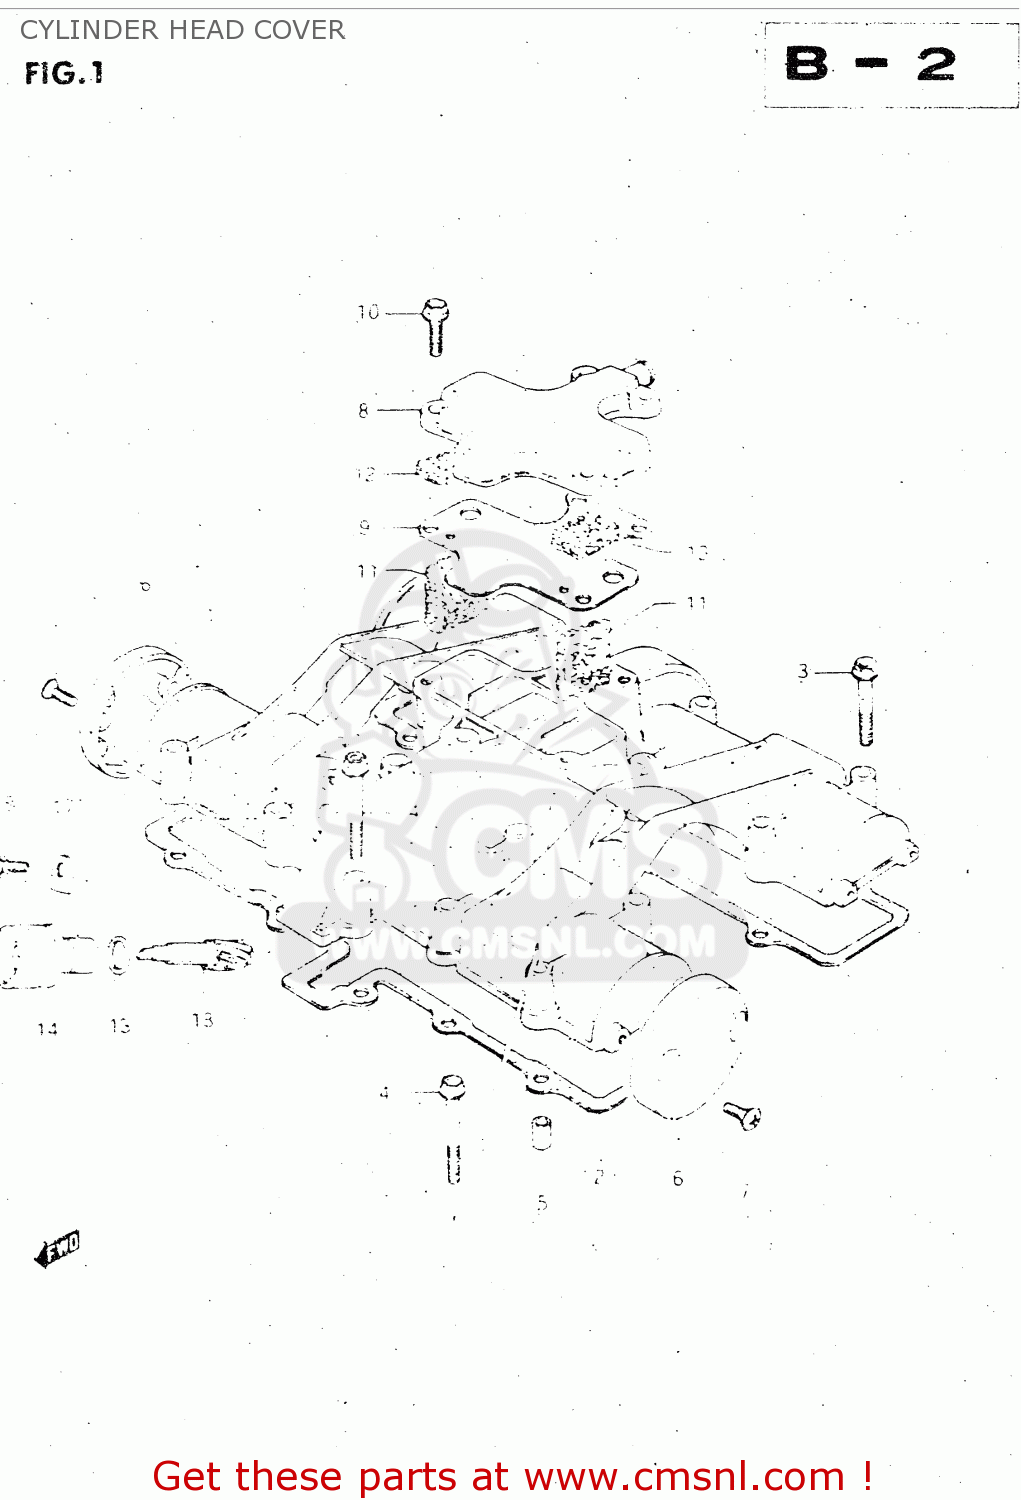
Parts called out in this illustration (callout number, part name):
1	COVER,CYLINDER HEAD
2	GASKET,CYLINDER HEAD COVER (MCA)
3	BOLT
4	BOLT,UNDER
5	PIN(6.2X8X11)
6	CAP,CYLINDER HEAD COVER
7	SCREW(5X12)
8	COVER,BREATHER
9	GASKET (MCA)
10	BOLT,REAR
11	COVER,BREATHER
12	SEPARATOR,OIL BREATHER
13	GEAR,TACHOMETER DRIVEN
14	SLEEVE,TACHOMETER DRIVE GEAR
15	SEAL,TACHOMETER DRIVEN
16	SEAL,OIL(5X12X8)
17	PLATE,TACH DRIVE GEAR SLEEVE
18	SCREW(5X12)
